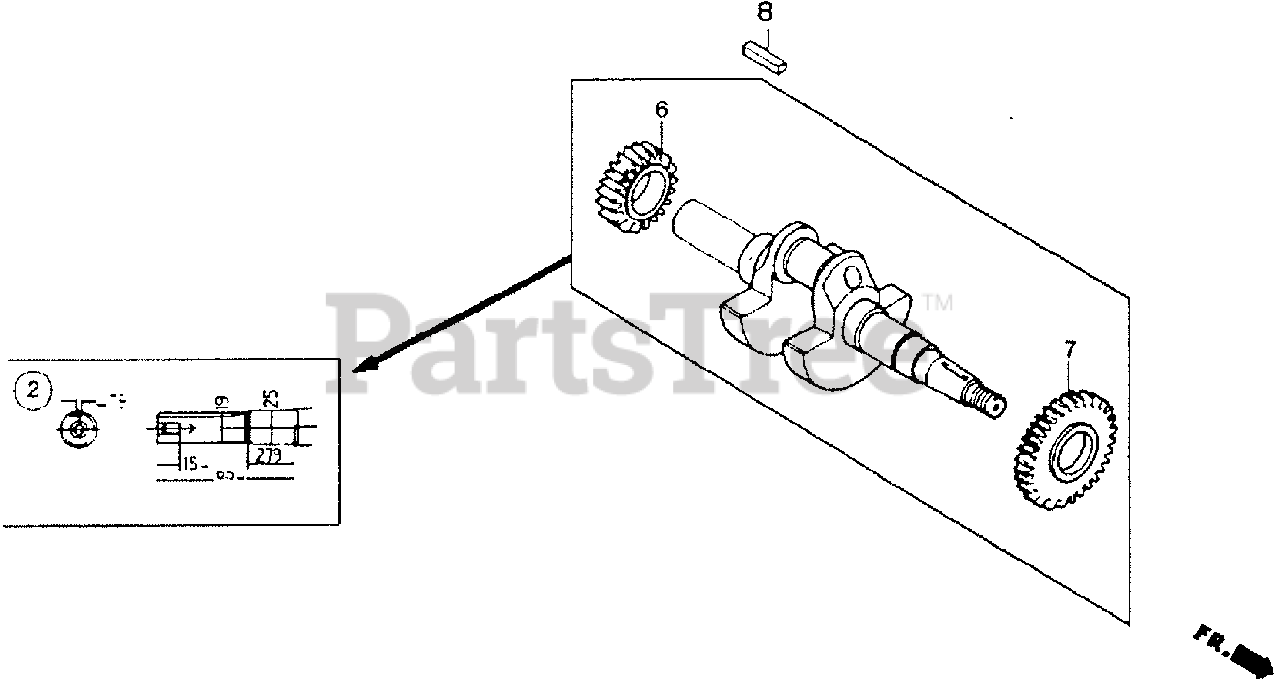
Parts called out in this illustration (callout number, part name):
2	CRANKSHAFT (Q-TYPE)
6	GEAR, TIMING
7	GEAR, GOVERNOR DRIVE
8	KEY (4.78X4.78X38)
